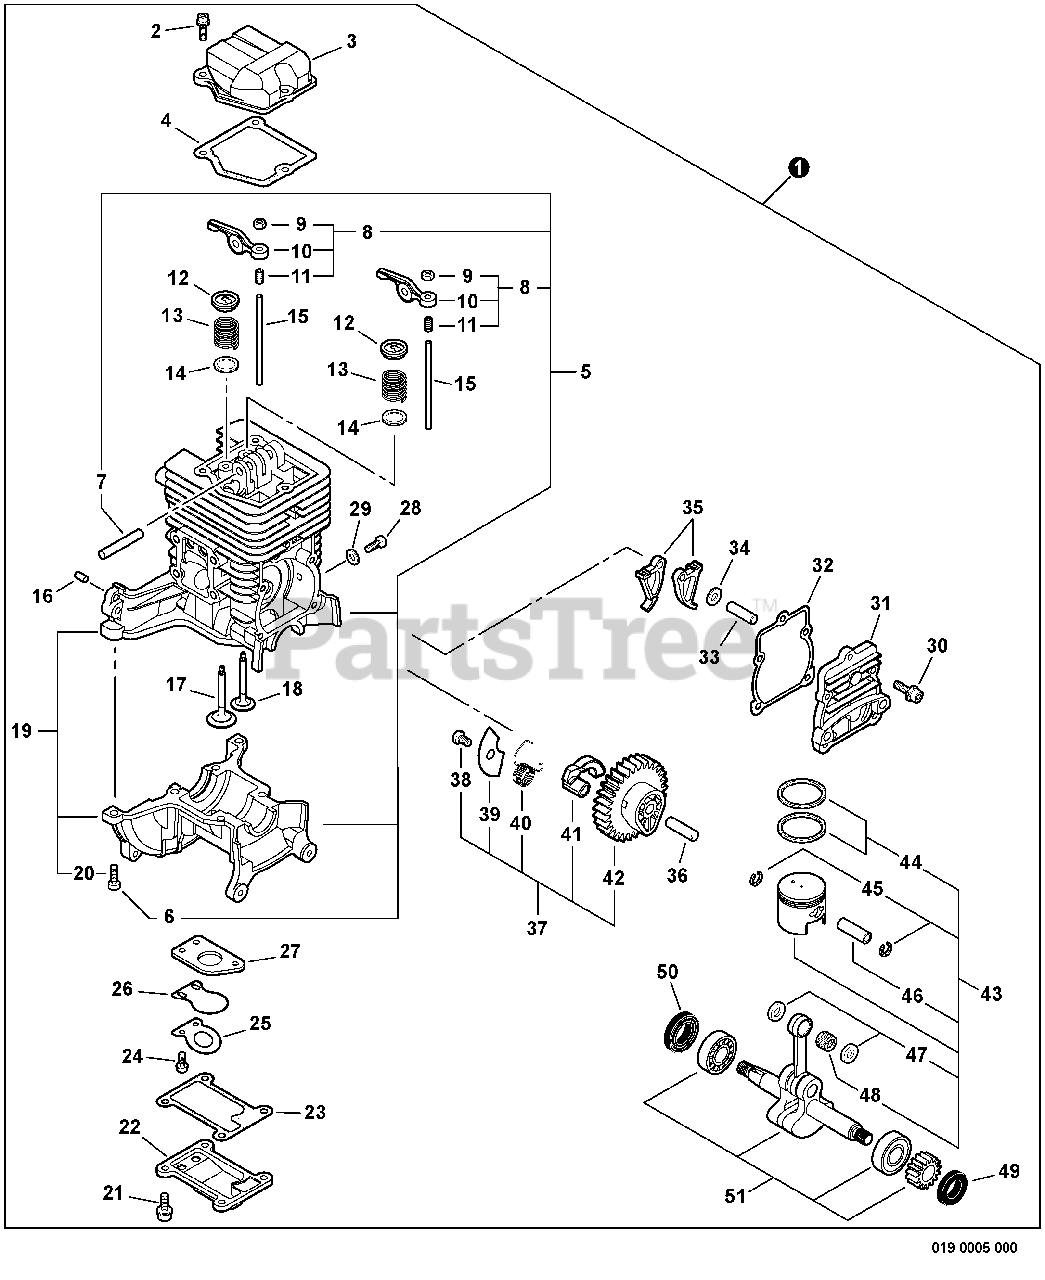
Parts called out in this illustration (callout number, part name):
1	SHORT BLOCK
2	BOLT M4×14
3	COVER, ROCKER ARM
4	GASKET, ROCKER ARM
5	CYLINDER & CRANKCASE ASSY
6	BOLT 5×16
7	SHAFT, ROCKER ARM Ø5×31.8 MM
8	ARM ASSY, ROCKER
9	NUT, ADJUSTER LOCK 5
10	ARM, ROCKER
11	SCREW, ADJUSTER
12	RETAINER, VALVE
13	SPRING, VALVE
14	WASHER, VALVE 9
15	PUSHROD
16	PIN, LOCATING Ø4×8
17	VALVE, INTAKE
18	VALVE, EXHAUST
19	CYLINDER & CRANKCASE ASSY
20	BOLT 5×16
21	BOLT M4×12
22	COVER, REED VALVE
23	GASKET, REED VALVE
24	SCREW M3×10
25	STOP, REED VALVE
26	VALVE, REED
27	PLATE, REED BACKING
28	SCREW M5
29	WASHER Ø10ר5.5×2
30	BOLT M4×14
31	COVER, CAM GEAR
32	GASKET, CAM GEAR
33	PIN, LOCATING Ø5×29.8 MM
34	WASHER 5 MM
35	FOLLOWER, CAM
36	PIN, LOCATING Ø5×29.8 MM
37	CAM GEAR ASSY
38	SCREW, TAPPING 4×6
39	PLATE, COVER
40	SPRING, COIL
42	GEAR, CAM
43	PISTON KIT
44	RING, PISTON
45	RING, SNAP
46	PIN, PISTON
47	WASHER, THRUST 9
48	BEARING, NEEDLE 9
49	SEAL, OIL 12
50	SEAL, OIL 12
51	CRANKSHAFT ASSY
